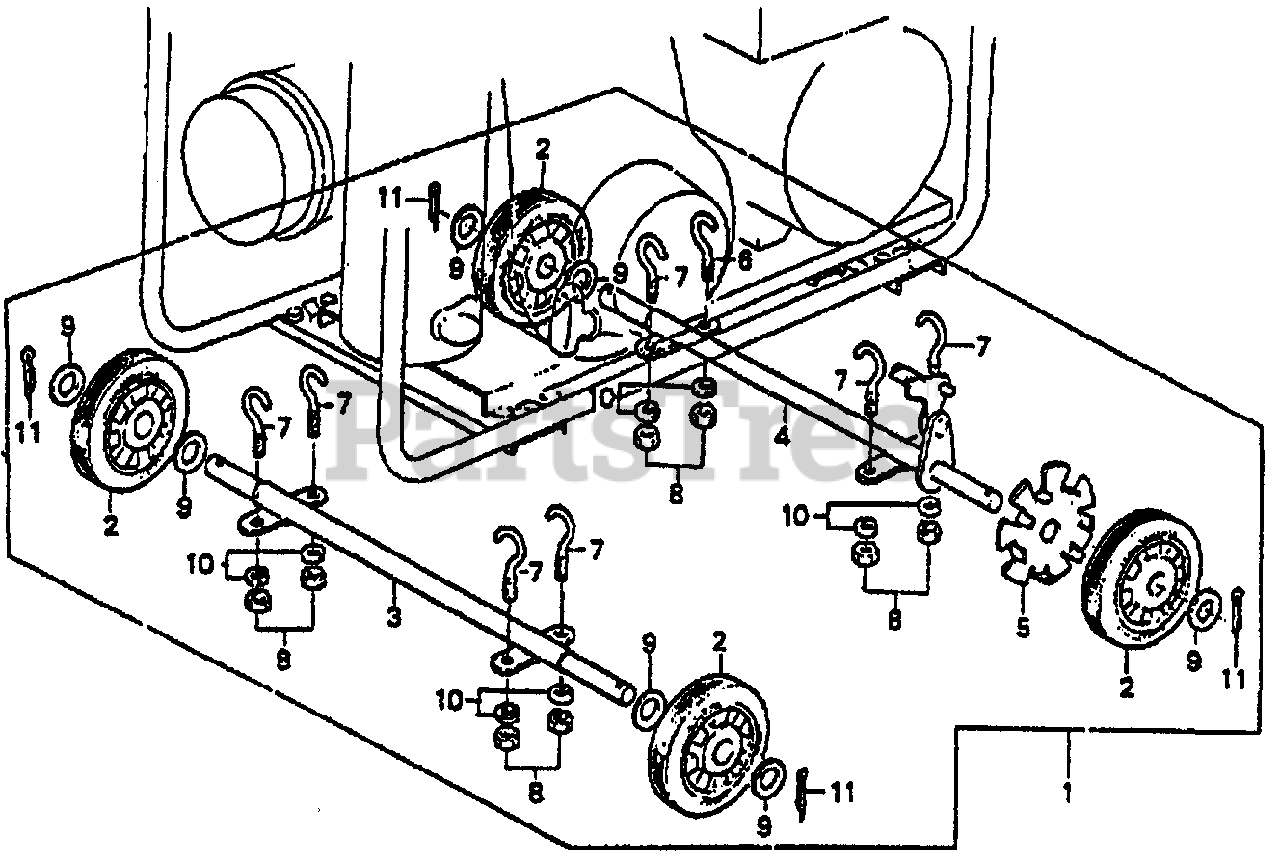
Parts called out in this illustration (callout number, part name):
2	WHEEL
3	SHAFT A, WHEEL (NOT AVAILABLE)
4	SHAFT B, WHEEL
5	PLATE, LOCK
6	BOLT A, HOOK
7	BOLT B, HOOK (NOT AVAILABLE)
8	NUT, HEX. (8MM)
9	WASHER, PLAIN (20MM)
10	WASHER, SPRING (8MM)
